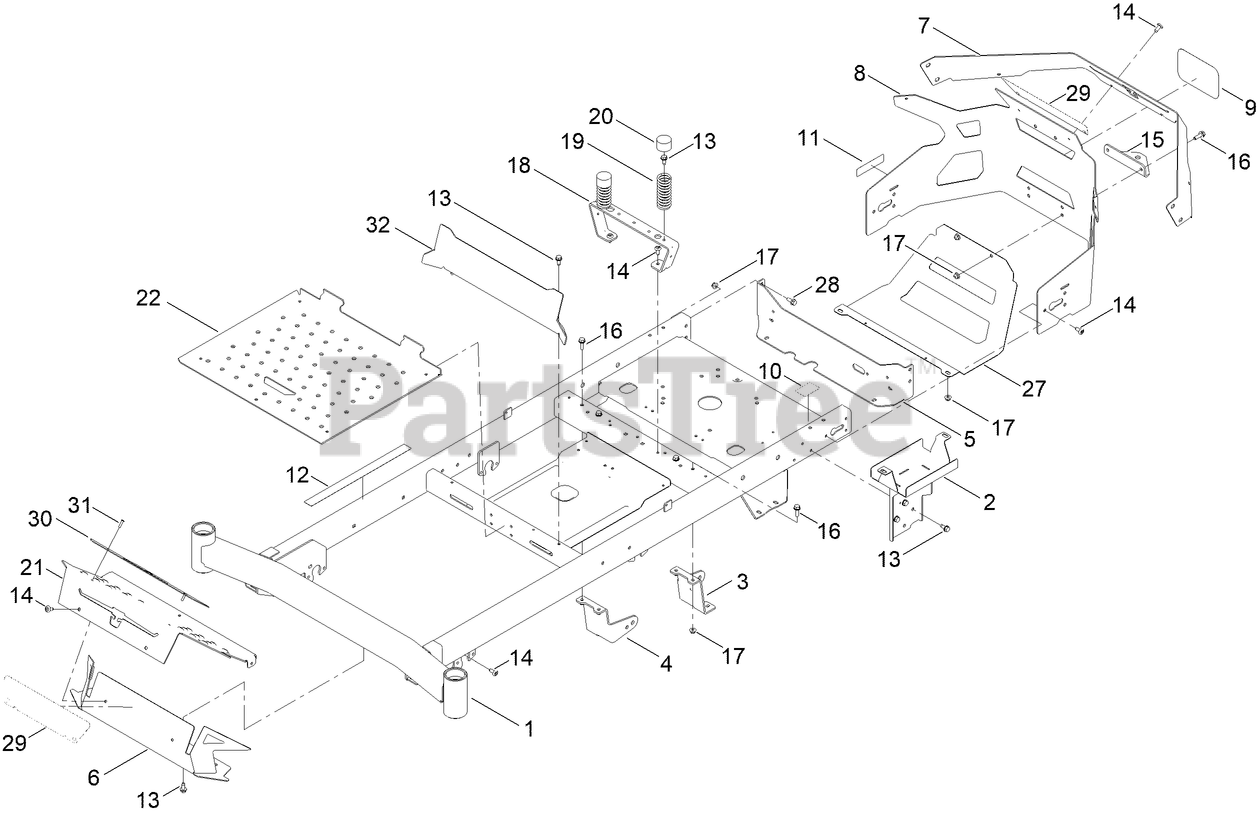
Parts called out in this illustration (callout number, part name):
1	SERVICE ASM-FRAME, TC
2	WA-BATTERY MOUNT
3	MOUNT-DRIVE, LH
4	MOUNT-DRIVE, RH
5	PLATE-MOUNT
6	FOOTREST-TOP
7	PLATE-REAR CLADDING TC
8	GUARD-ENGINE TC
10	DECAL-BYPASS
11	DECAL-SPARK ARRESTER
12	DECAL-WARNING
13	SCREW-HWHTF
15	BRACKET-HITCH
16	SCREW-HHF
17	NUT-HF
18	SUPPORT-SEAT
19	SPRING-COMPRESSION
20	CAP-PROTECTOR
21	PLATE-KICK
22	PAN-FLOOR
27	GUARD-MUFFLER [BLACK]
28	SCREW-HHF
29	DECAL-BACKER, RED
30	PLATE- TOEBOARD
31	RIVET-TRIFOLD
32	PLATE-KICK
